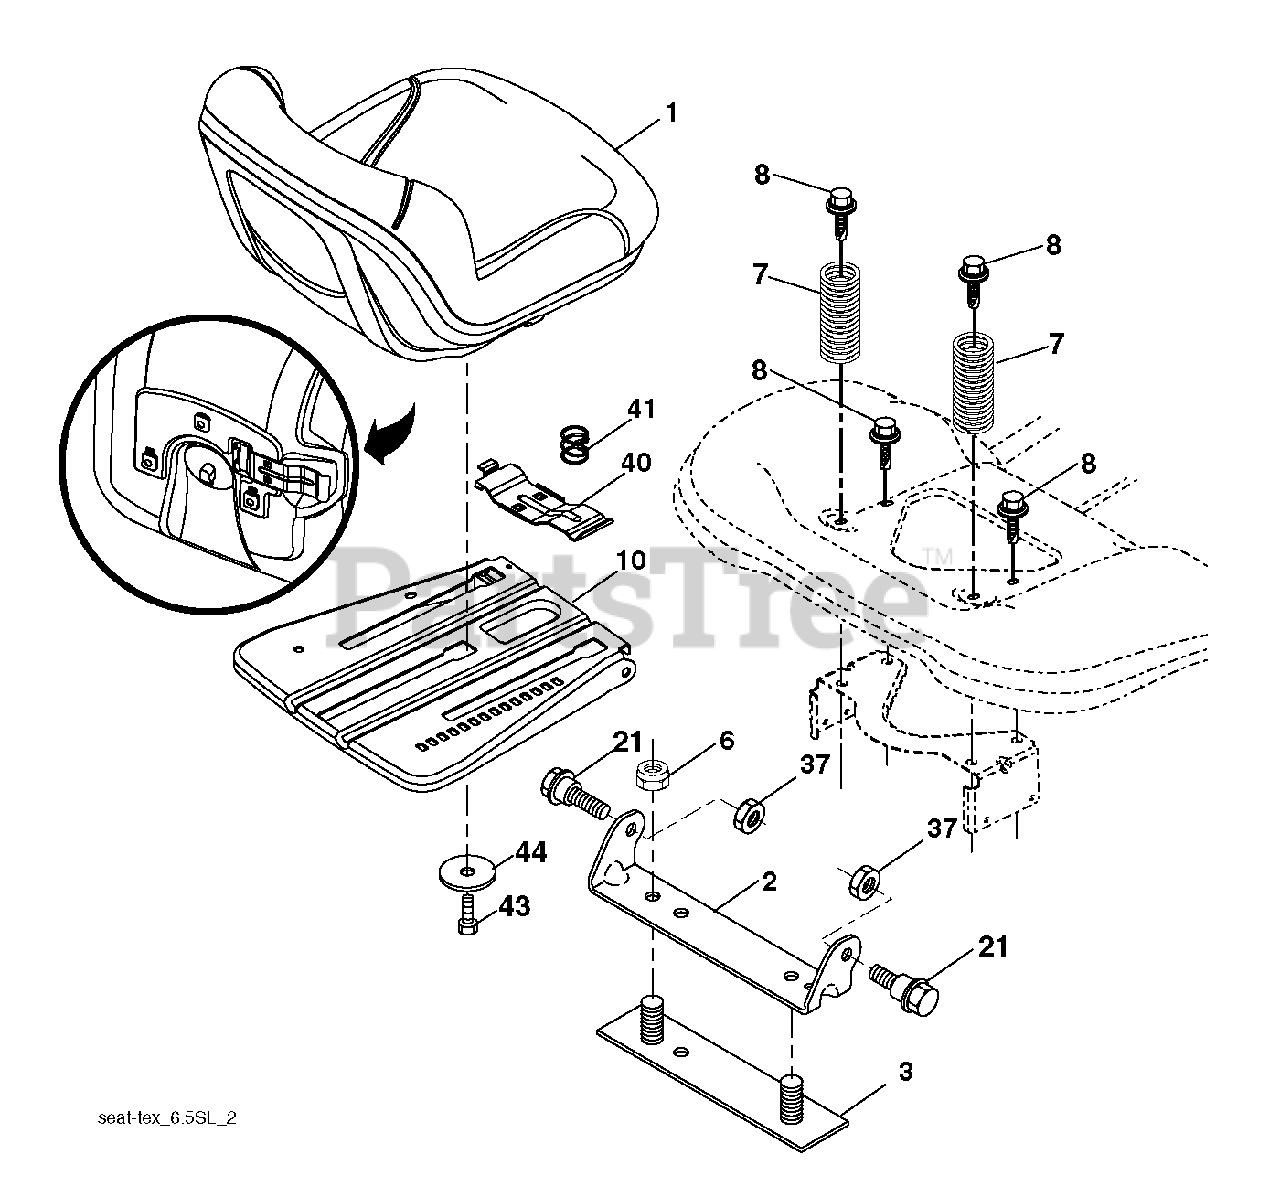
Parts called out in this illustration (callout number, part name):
2	BRKT.PIVOT.FENDER
3	STRAP
8	BOLT, 5/16-18 X 1 3/4
10	PAN.ASM.SEAT.3PT
21	BOLT, SHOULDER
40	HANDLE.SLIDE.SEAT.TEX.
41	SPRING.LATCH.SEAT.TEX
44	WASHER 13/32 X 2-3/8 X 12GA
